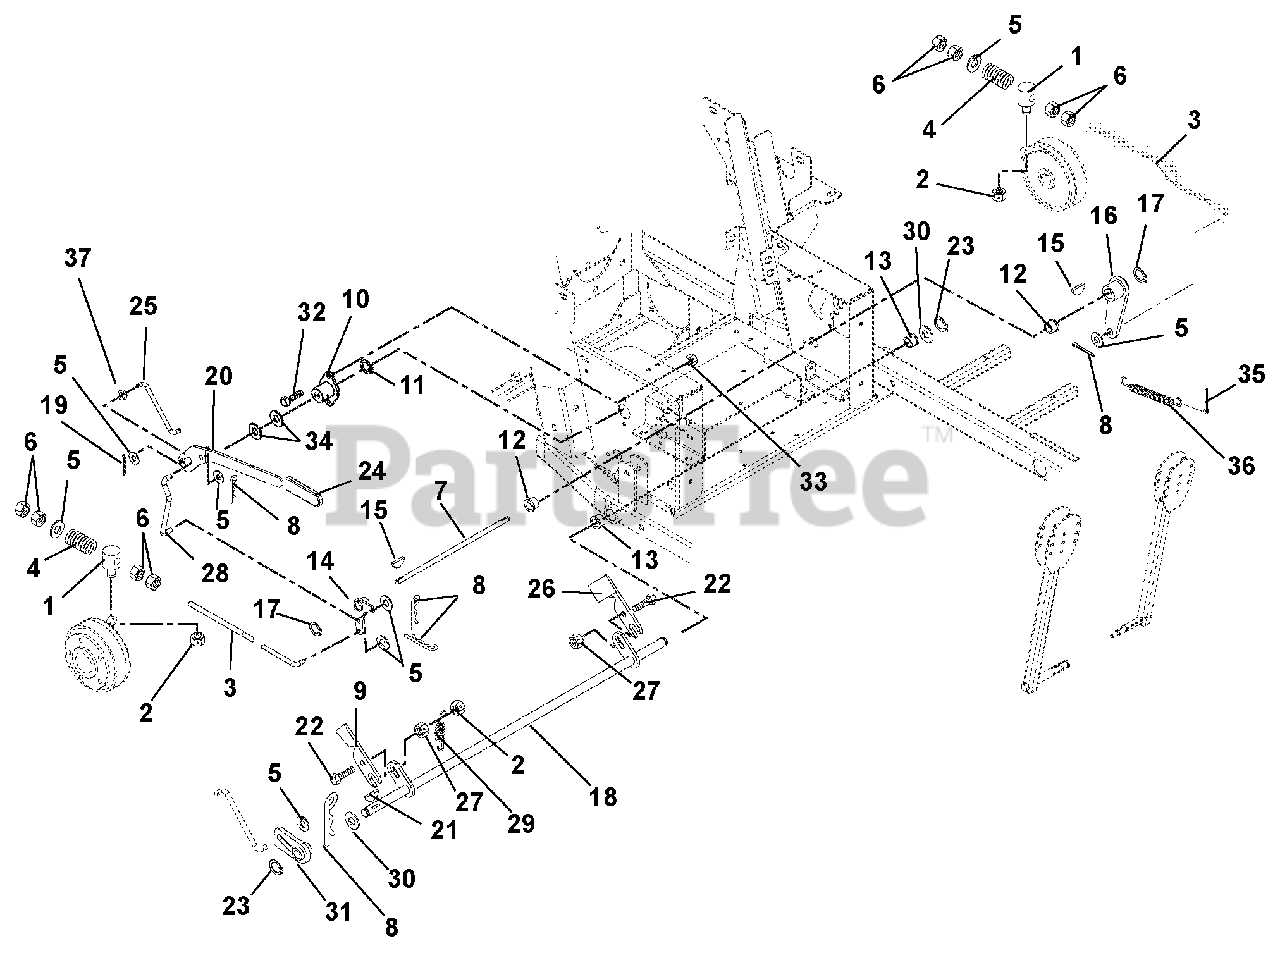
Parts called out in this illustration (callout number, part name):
1	Pivot, Brake Rod
2	Nut, Locking Center .31-18
3	Weldment, Brake Rod PM200 Diesel
4	Spring, Compression .142 x .710 x 1.75
5	Washer, Flat Steel .406 x .812 x .065
6	Nut, Hex .38-16
7	Shaft, Brake Cross
8	Pin, Hair
9	Slide, Interlocking Brake
10	Bushing, Flange
11	Ring, Retaining External .625 x .05
12	Bushing, Flange Nylon .762 x 1.00 x .58 x 1.48
13	Bushing, Flange .515 x .75 x .745 x 1.00
14	Weldment, 200 Brake Actuating Arm
15	Key, Woodruff .19 x 1.00 x .19 SAE 8630
16	Arm, Brake
17	Ring, Retaining External .69 x .077
18	Weldment, Mechanical Brake
19	Pin, Cotter External .09 x .75
20	Weldment, Handle
21	Key, Woodruff .13 x .63
22	Bolt, Round Head Square Neck .31-18 x 1.25 Grade 5
23	Ring, Retaining External .50 x .05
24	Grip, Handle
25	Linkage, Brake Actuating
26	Interlock, Safety Switch
27	Nut, Locking Top Flange .31-18
28	Linkage, Brake Actuating
29	Spring, Tension
30	Washer, Flat Steel .505 x 1.00 x .062
31	Weldment, Parking Brake Hub
32	Bolt, Hex .31-18 x .75 Grade 5
33	Nut, Locking Top Flange .31-18
34	Washer, Flat Steel .630 x 1.25 x .062
35	Pin, Cotter .12 x .75 Extended Prong Square Cut
36	Spring, Extension
37	Bushing, Sleeve .377 x .624 x. 235
